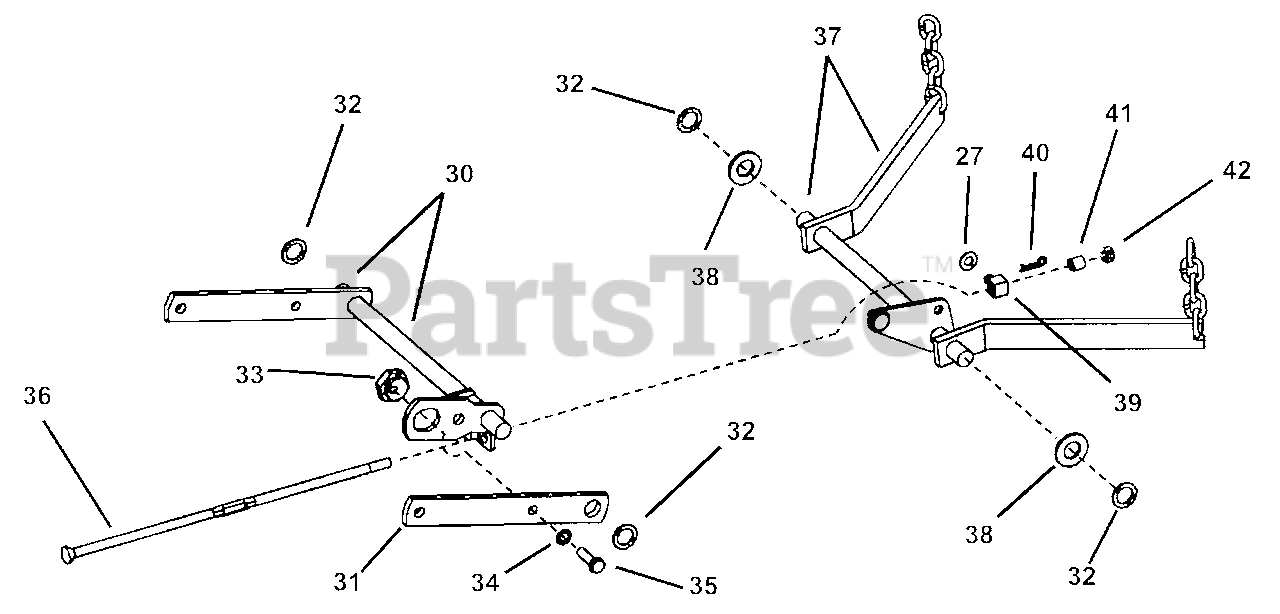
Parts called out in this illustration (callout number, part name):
27	WASHER, 3/8" Flat
30	LIFT ARM, Front (weldment)
31	LIFT ARM, Front
32	WASHER, 3/4" x 1-1/8"
33	ECCENTRIC, Leveling
34	WASHER, 3/8" Int. Tooth Lock
35	SCREW, 3/8-24 x 1-1/4" Hex Head Cap
36	ROD, Cutter Deck Timing
37	LIFT ARM, Rear (weldment)
38	WASHER, 3/4 I.D. x 1-1/2" O.D. Flat
39	SWIVEL, Brake Link
40	HAIR PIN, #13
41	SPACER, MF1200
42	NUT, 3/8-16 Hex Center Lock
